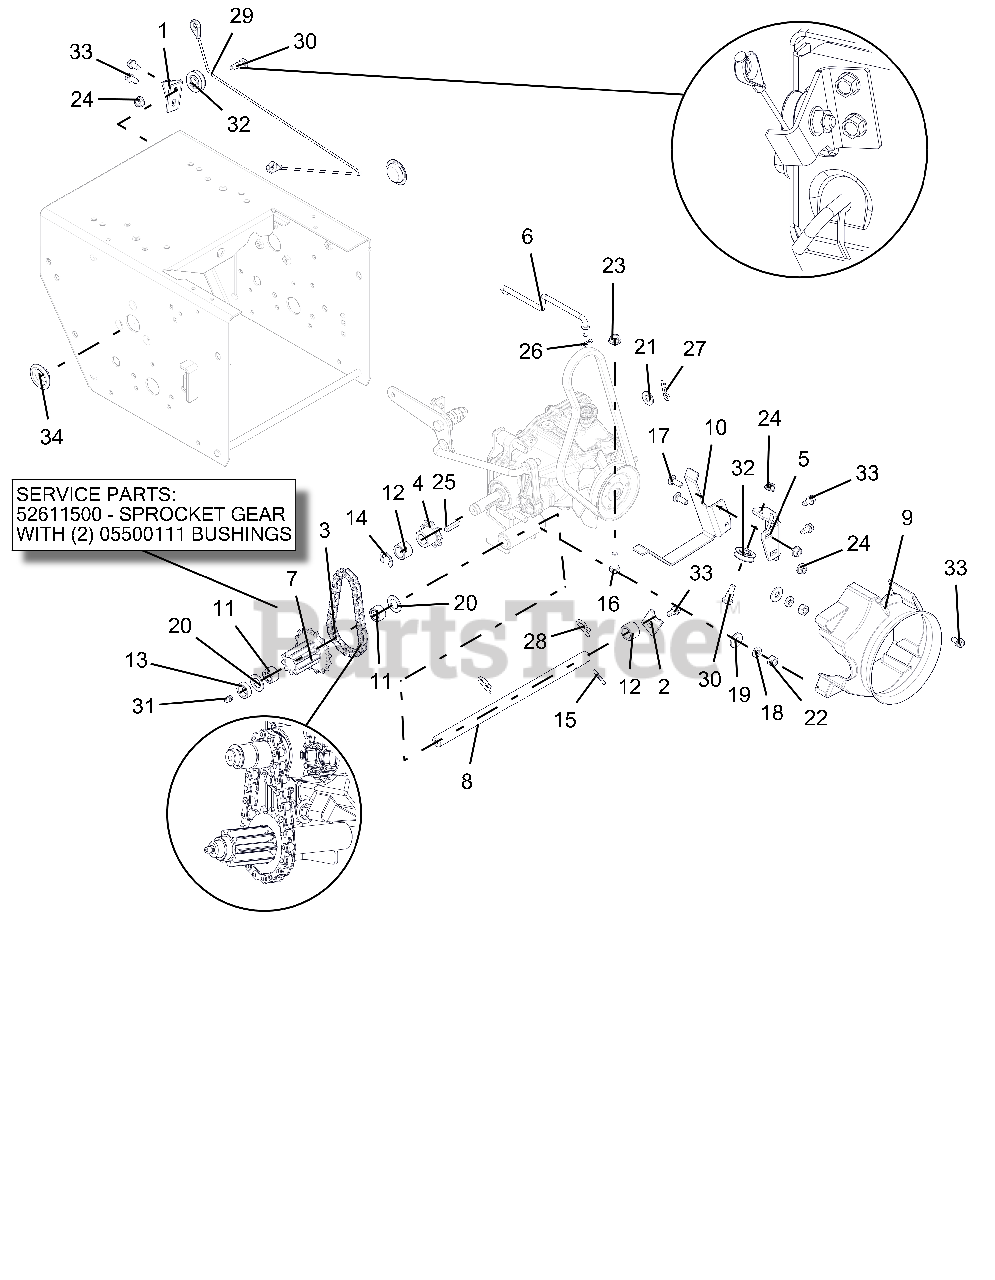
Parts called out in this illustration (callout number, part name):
1	BRACKET, CABLE PULLEY
2	TAB, ANTI ROTATION
3	CHAIN-ROLLER #41X26 PITCHES
4	SPROCKET, PINION 9T W/KEY
5	BRACKET, CLUTCH CABLE
6	ROD, HYDRO BYPASS
7	PINION & SPROCKET (16T & 9T)
7	PINION & SPROCKET W/BEARINGS
7	BSHG-FLG .625X.750X.500X.875
8	SHAFT, PINION - HARDENED
9	SHROUD, HYDROGEAR RT-310
10	FINGER, BELT - FLAT
11	BRG-NEEDLE .625X.812X.50
12	SPACER, .635X.880X.611
13	BSHG-SLV, .635X.880X.305
14	RG-RTNG-EXT .625X.042
15	@PIN-GRV .125X1.00 TP E ALLOY
16	@BLT-HEX .31-18X1.00 GR5 YWZC
17	@BLT-RDHDSQNK .25-20X.75 G5YZ
18	WSHR-LK .312X.097 HVY YWZC
19	@WSHR-FL-STL.38X.875X.083 YWZC
20	WSHR-FL-STL .630X1.005X.062 YZ
21	@WSHR-FL-STL.406X.812X.065 YWZ
22	@NUT-HEX .31-18 YWZC
23	@NUT-LK-TOP-FLG .31-18 YWZC
24	@NUT-LK-TOP-FLG .25-20 YWZC
25	KEY-SQ .188X1.0X.188 SAE 8630
26	PIN-HAIR INT .06X.18X.77
27	PIN-HAIR INT .08X.18X1.18 YWZC
28	PIN, SPRING CLIP
29	CABLE, TRACTION, HYDRO PRO
30	BOLT, SHLDR-.375X.375X.25-20
31	ZERK,FITTING .25X.125 DRIVE IN
32	PULLEY, CABLE
33	SCR-TAP .25-20X.50 HWH TR YWZ
34	PLUG, HOLE - 1.125"
